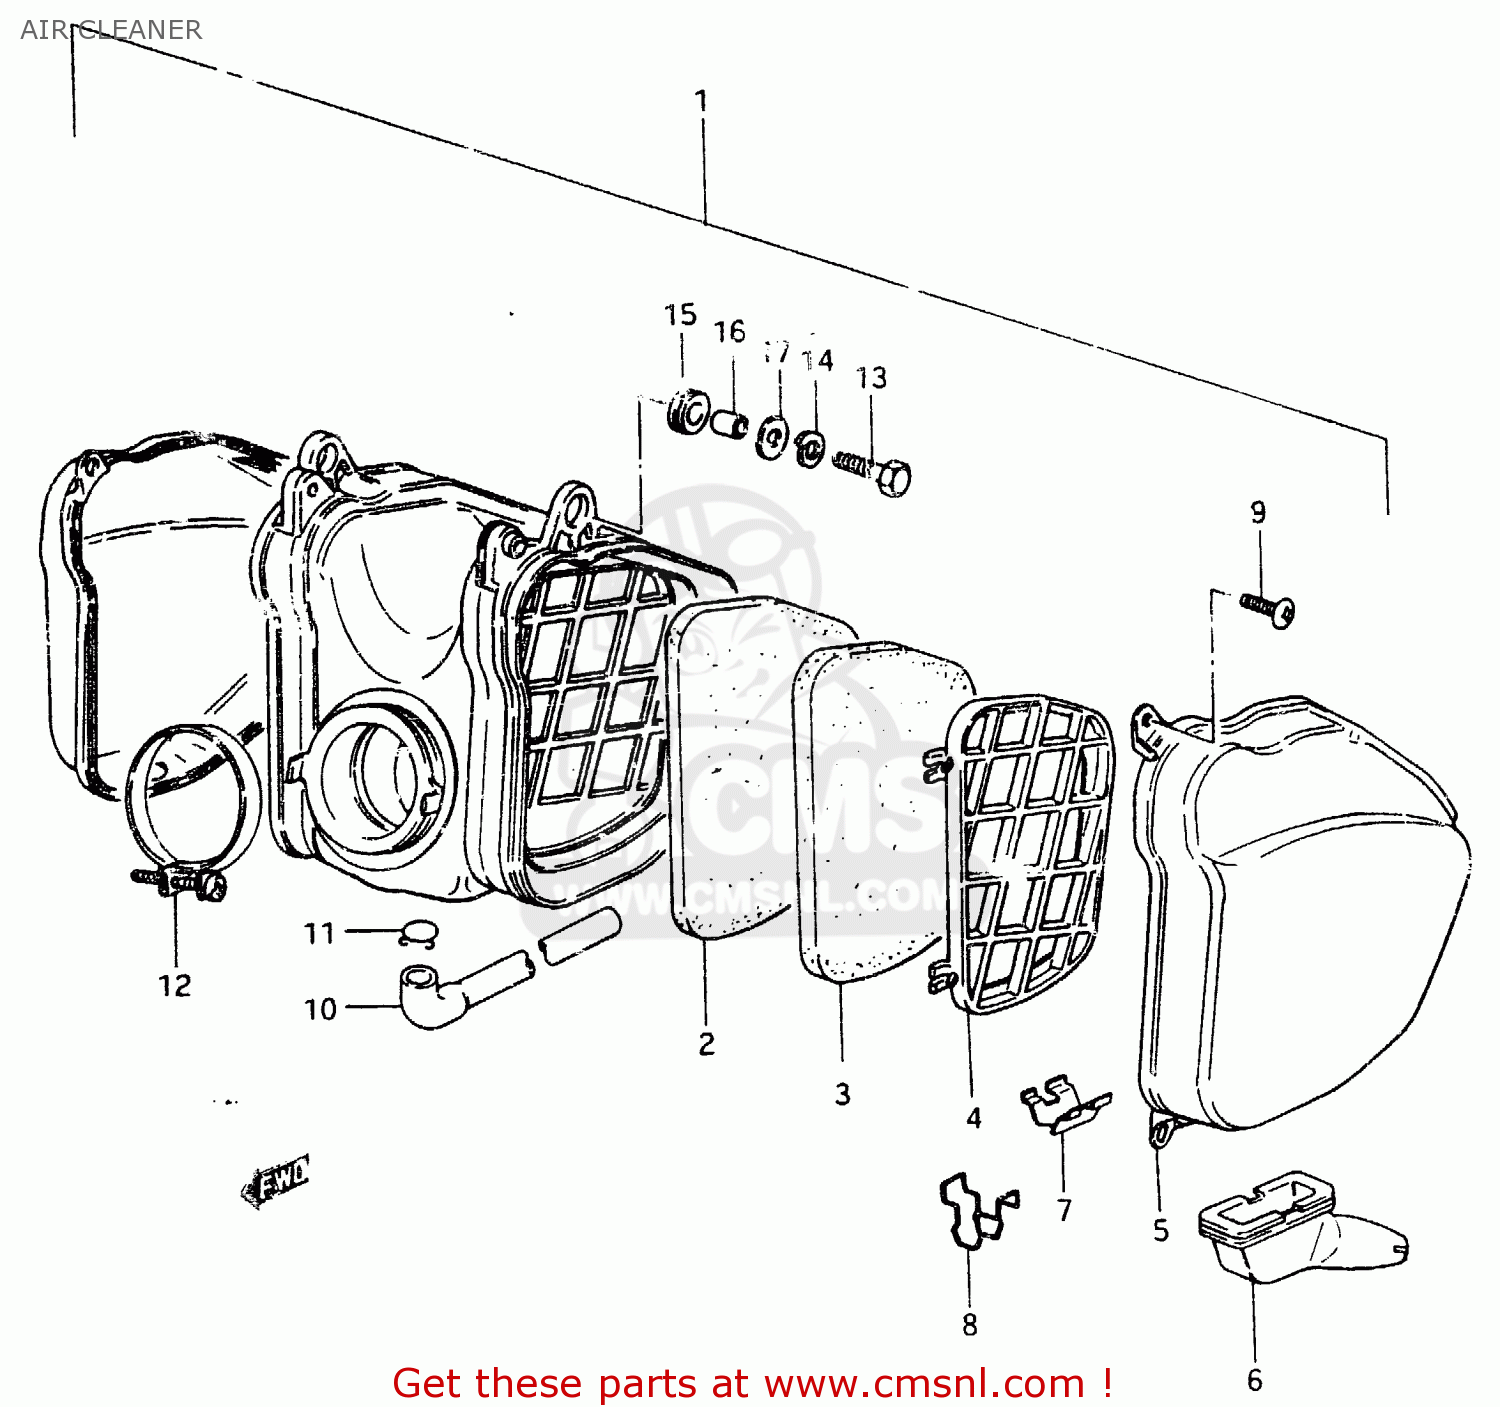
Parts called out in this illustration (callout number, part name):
1	CLEANER ASSEMBLY,AIR
2	FILTER
3	FILTER,2ND
4	HOLDER,FILTER
5	CAP,AIR CLEANER
6	DRAIN TUBE
7	DRAIN STOPPER
8	DRAIN STOPPER
9	SCREW
10	DRAIN TUBE
11	CLIP
12	CLAMP
13	BOLT
14	LOCK WASHER
15	CUSHION
16	SPACER (7X9X7)
17	WASHER
